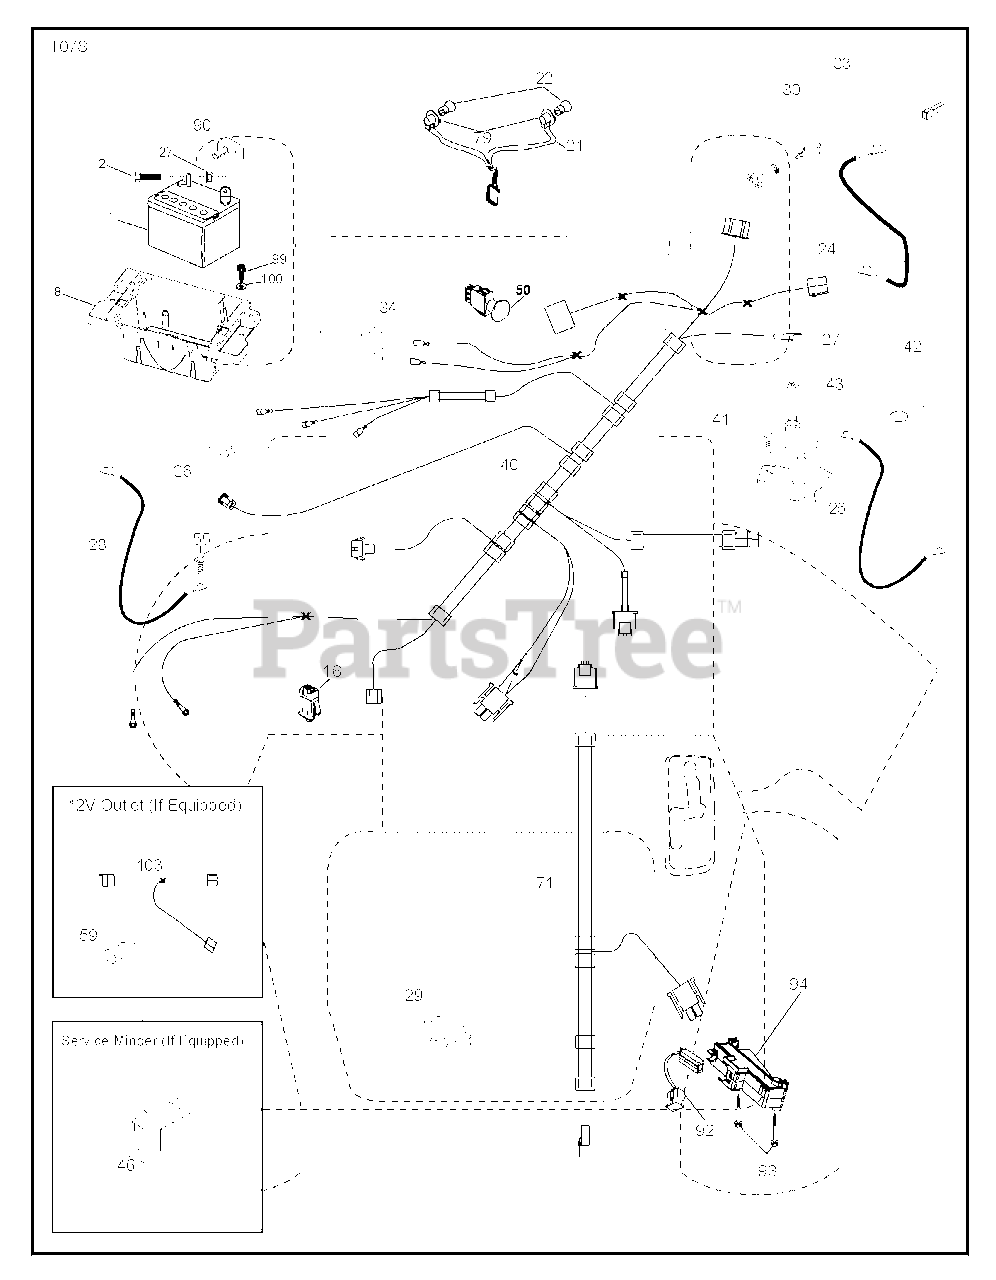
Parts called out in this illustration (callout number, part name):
1	REPL BY 532 12 38-99
2	BOLT.HEX.1/4.X.3/4.DICHROMATE
8	TRAY.BATTERY BOX.FRONT
16	SWITCH INTERLOOK PUSH-IN
21	HARNESS ASSY LIGHT
22	LIGHTBULB
24	Battery Cable with Wire, Front 8 Ga 8
25	Starter Cable, 8 Ga 17.5"
26	FUSE 20AMP
27	NUT
28	Ground Cable, 21" Black 8 Ga 90T
29	SWITCH.SEAT.DELTA.OPC.
30	SWITCH.IGN.DELTA.W.LGH.ROS
33	KEY.CHAIN.BLISTER.PACK.GEN.USA
34	SWITCH LT
40	HARNESS HARNESS..DASH.ING.ELEC
41	SCREW
42	TERMINAL COVER
43	SOLENOID.W/BRASS.PLUNGER
46	Hour Meter Gauge
50	RP SWITCH.PTO.TERMINAL.STD.RED
55	SCREW 5/16"
71	HARNESS-CHASSIS SUB
79	BULB HOLDER ASM.
90	COVER.TERMINAL.BATTERY
92	HARNESS.PIGTAIL.CONSLE
93	SCREW.PLASTITE
94	MODULE.REVERSE.ROS
99	SCREW HEXWSHR 1/4-20X3/4
